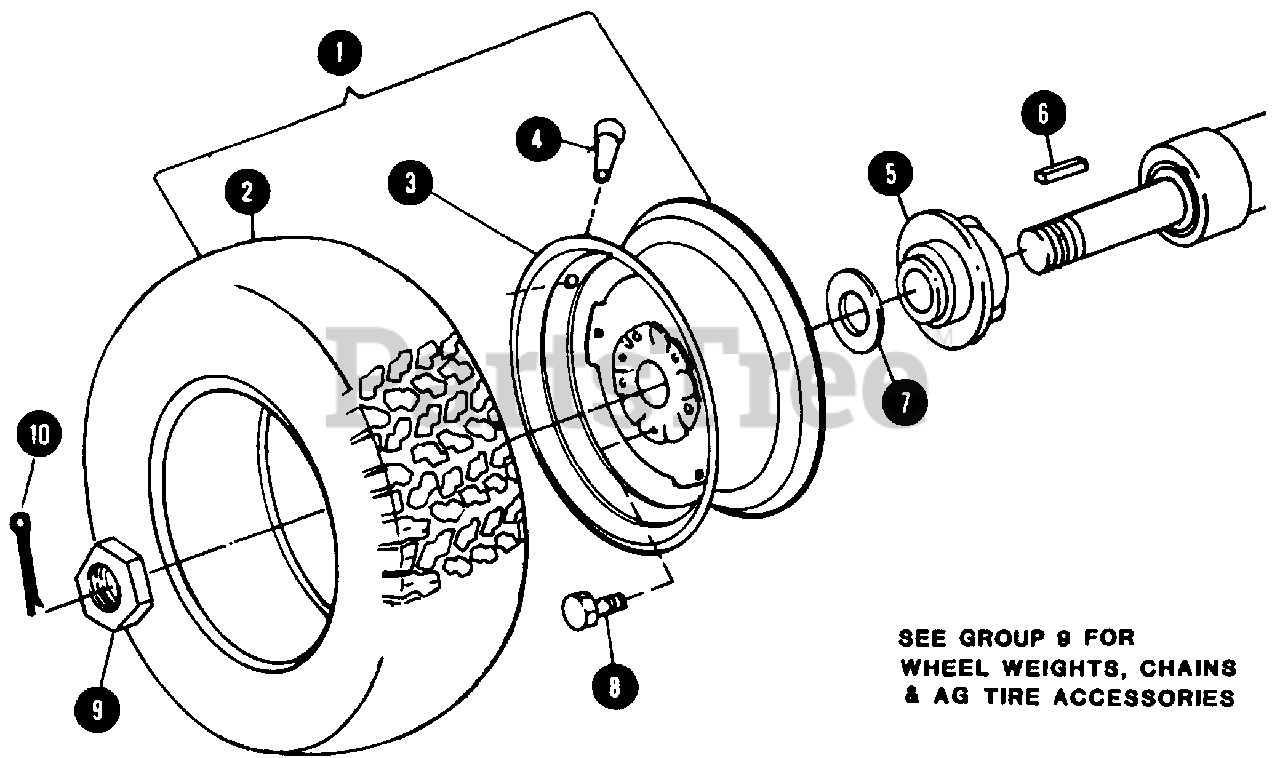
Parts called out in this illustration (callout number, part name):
1	WHEEL ASSEMBLY
2	TIRE, 26 x 12 x 12
4	VALVE, AIR
5	HUB, REAR WHEEL
7	WASHER, 3/4" FLAT
8	BOLT, RIM TO HUB
9	NUT, 3/4-16 UNC
10	COTTER-PIN, 3/16 x 1-1/4
